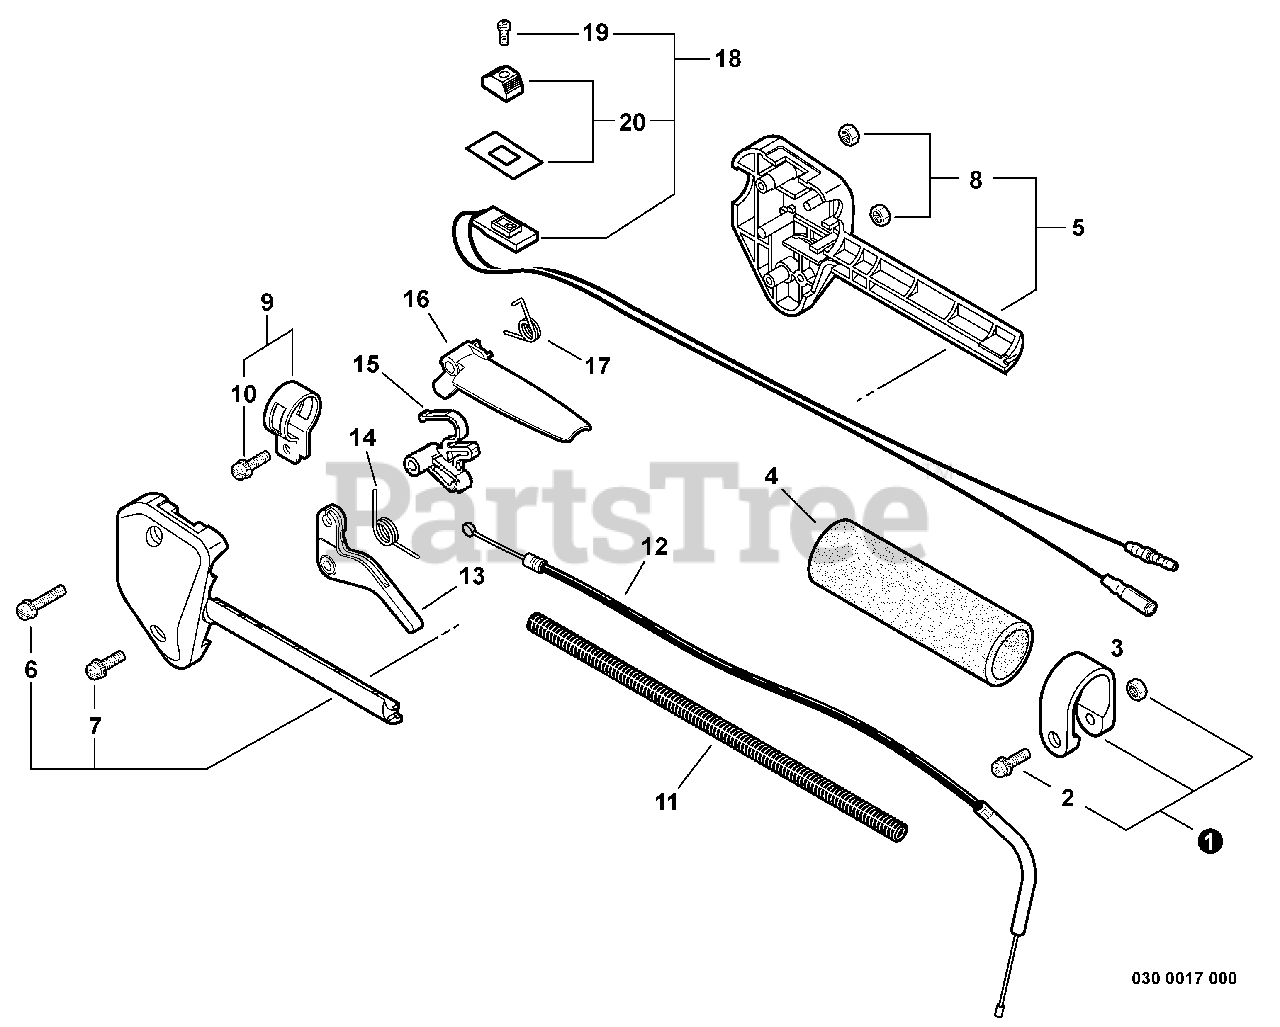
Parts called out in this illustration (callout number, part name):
1	CLAMP KIT
2	SCREW - 5X28
4	GRIP, HANDLE
5	CONTROL HANDLE KIT
6	SCREW - 5X35
7	SCREW - 5X25
9	CLAMP KIT
10	SCREW - 5X14
11	TUBE, PROTECTIVE - CORRUGATED
12	CABLE, THROTTLE
13	TRIGGER, THROTTLE
14	SPRING, TRIGGER
15	LOCKOUT, THROTTLE
16	LEVER, TRIGGER LOCKOUT
17	SPRING, LOCKOUT LEVER
18	IGNITION SWITCH ASSY
19	SCREW - 3X10
20	KNOB, SWITCH - ORANGE
